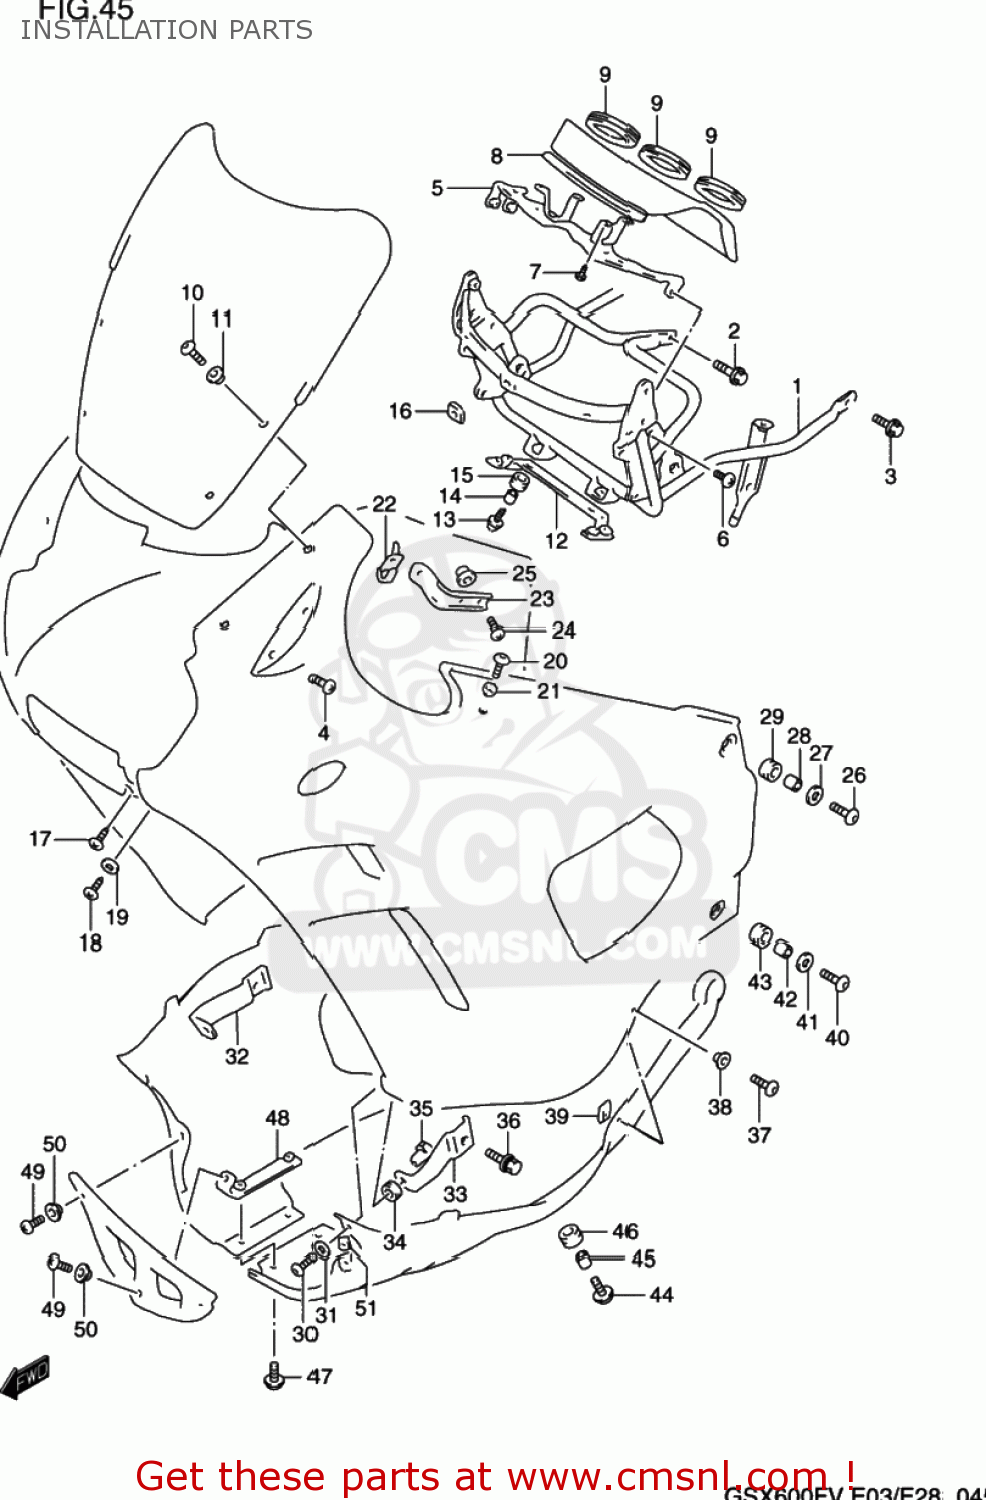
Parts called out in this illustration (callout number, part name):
1	BRACE,COWLING
2	BOLT(8X20)
3	BOLT
4	SCREW 6X12
5	PLATE,METER FITING
6	SCREW 6X12
7	SCREW 5X8
8	MOLDING,METER COVER
9	CUSHION,METER COVER
10	SCREW
11	WASHER
12	PLATE,COWL CTR PANEL
13	SCREW(6X20)
14	SPACER (6.5X10X9.4)
15	CUSHION
16	CUSHION,SCREEN
17	SCREW 5X12
18	SCREW(6X25)
19	WASHER
20	SCREW(6X16)
21	WASHER(6.3X16X1.5)
22	BRACKET,COWLING UPR,R
23	BRACKET,COWLING UPR,L
24	SCREW
25	NUT,COWLING SIDE BRKT
26	SCREW(6X25)
27	WASHER
28	SPACER(6.5X9X9)
29	CUSHION
30	SCREW(6X30)
31	WASHER
32	BRACKET,COWLING LWR,R
33	BRACKET,COWLING LWR,L
34	CUSHION
35	NUT,COWLING,FR
36	BOLT
37	SCREW(5X14)
38	WASHER(5.2X14X1.5)
39	NUT,HEADLAMP HOUSING,UPPER
40	SCREW(6X25)
41	WASHER
42	SPACER(6.1X9X12.3)
43	CUSHION
44	SCREW(6X20)
45	SPACER(6.5X9X9)
46	CUSHION
47	SCREW
48	BRACKET,FR UNDER COWL
49	SCREW
50	WASHER(5.2X14X1.5)
51	NUT,HEADLAMP HOUSING,UPPER
